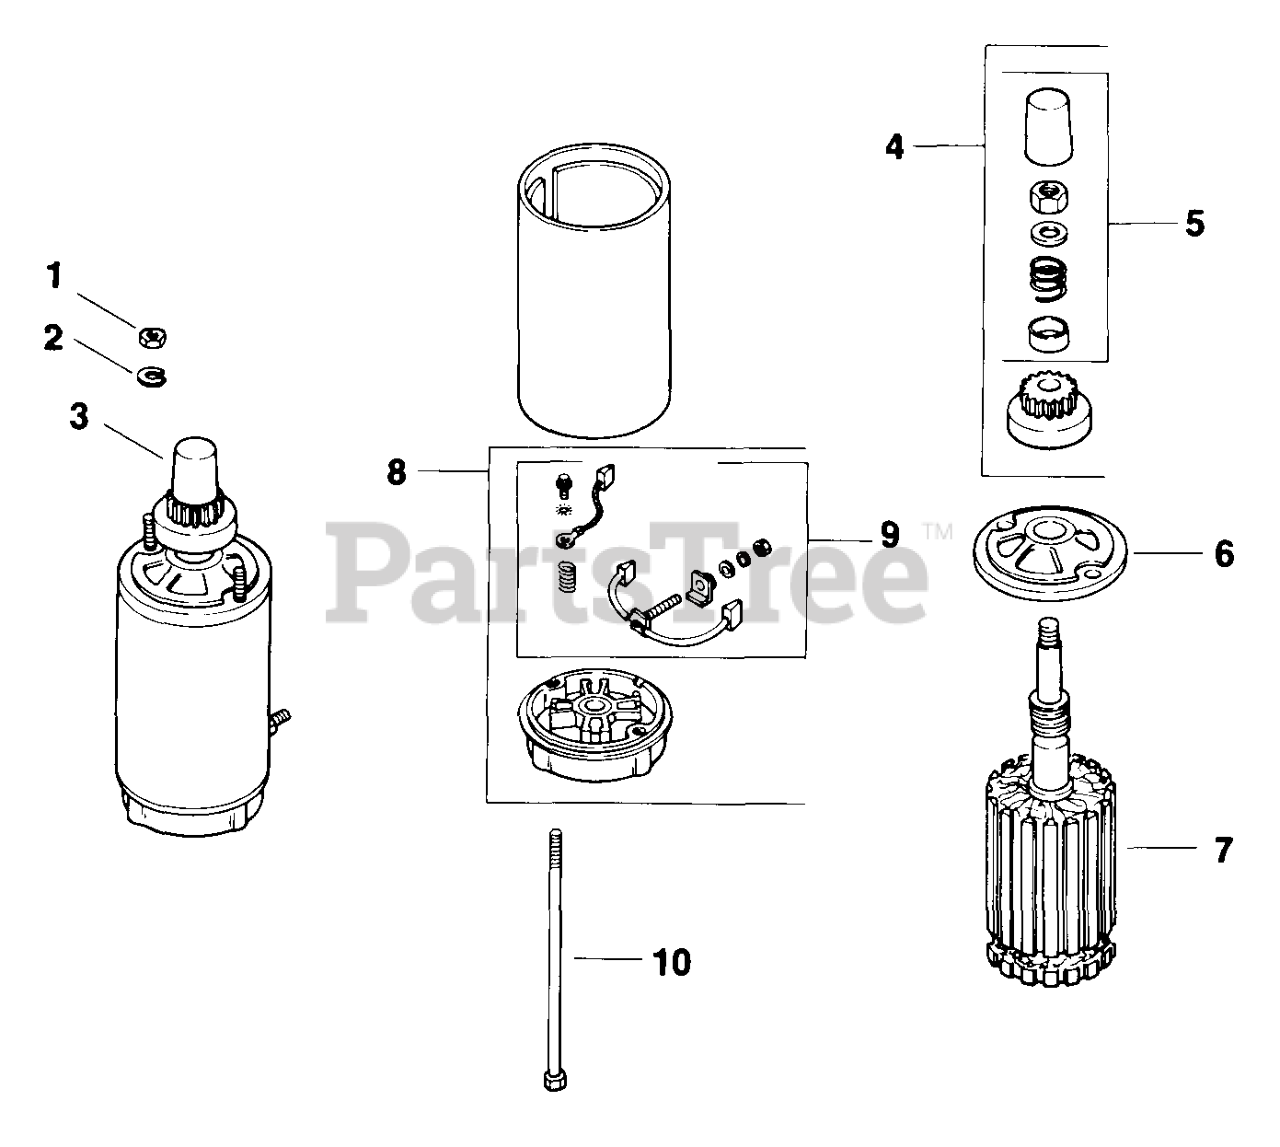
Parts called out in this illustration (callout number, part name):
1	Nut, Hex. 1/4-20
2	Washer, Lock 1/4"
3	Starter Assembly
4	Kit, Drive
5	Kit, Drive Parts
6	Cap, Drive End
7	Armature
8	Cap, Commutator End
9	Kit, Brush & Spring
10	Bolt, Thru 1/4-20x5-7/8"
